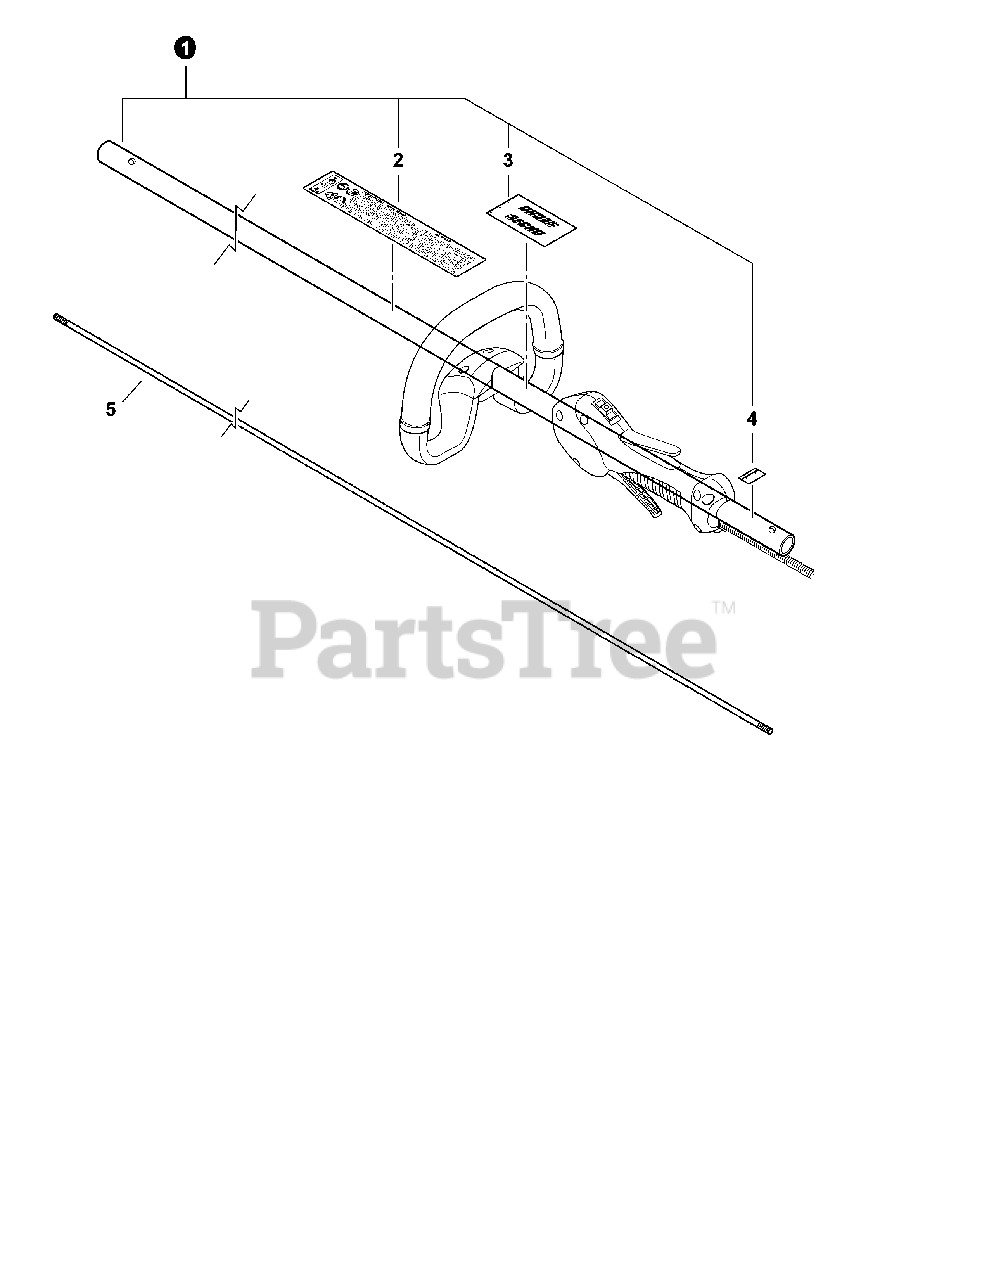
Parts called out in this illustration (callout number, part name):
1	MAIN PIPE ASSY
2	LABEL, CAUTION
3	LABEL, HANDLE LOCATION
4	LABEL - ALIGNMENT
5	DRIVESHAFT
